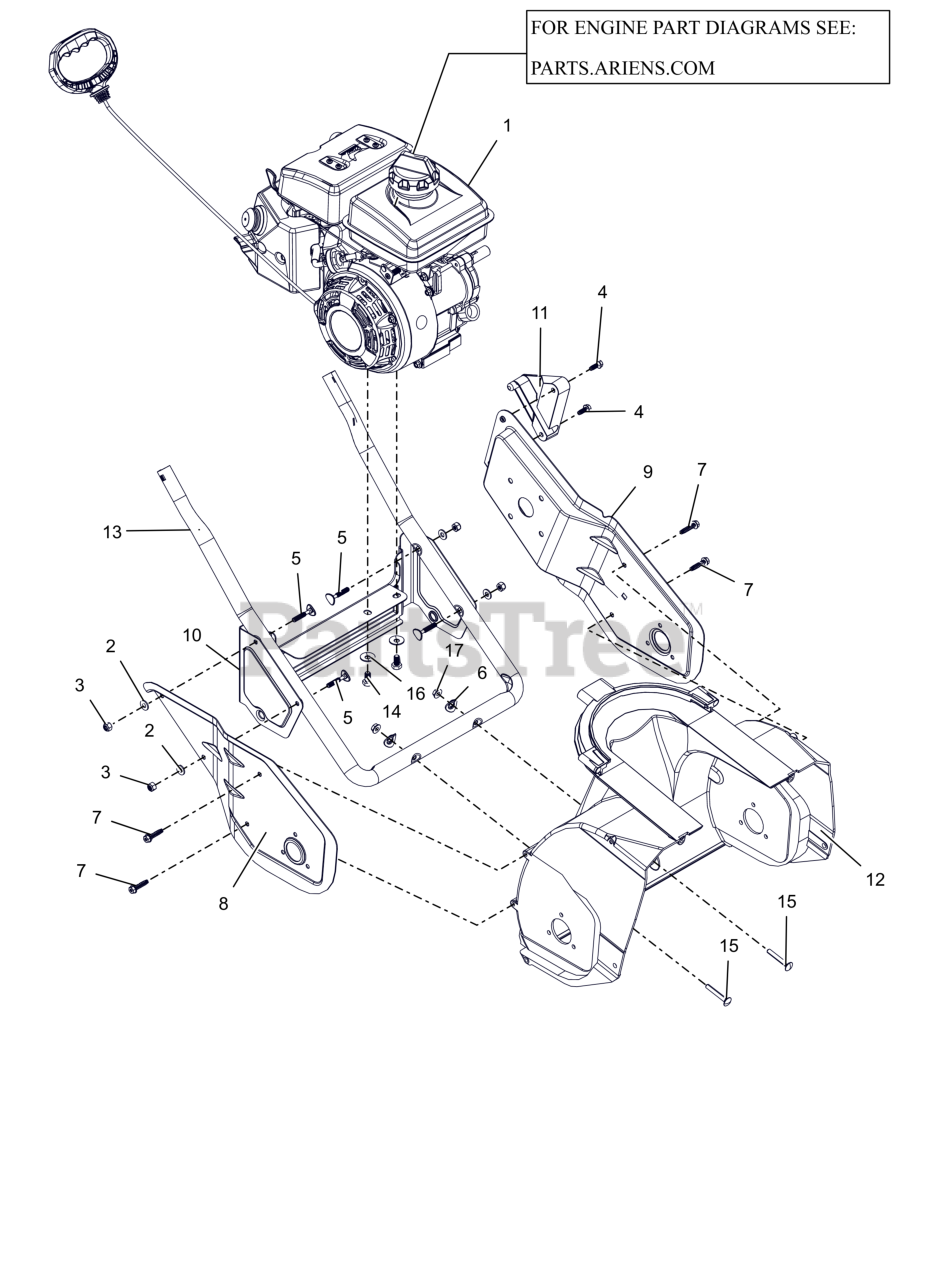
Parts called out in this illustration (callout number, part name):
1	ENGINE, LONCIN 99 PULL START
2	WSHR,FLT .281X.625X.065 ZCC
3	NUT, NYLON .250 - 20 (BLACK)
4	1/4-20 X 5/8 TAPTITE
5	HANDLEBAR, SCR - 1/4-20 - 1"DIA
6	WSHR, HANDLEBAR - 5/16
7	1/4"-10x1.12 TRI-LOBE SCREW
8	PLATE, SIDE - RH
9	PLATE, SIDE - LH
10	WHEEL, BRKT
11	BRKT, FENDER SUPPORT
12	HOUSING, LOWER
13	LOWER, HANDLEBAR
14	SCR, CAP - M8X1.25 H6 THREAD
15	BLT, RDHDSQSHK .25-20X1.75 (BLACK)
16	WSHR, BEVEL SPRING LOCK
17	NUT-LK-CTR-FLG .25-20 ZC120
